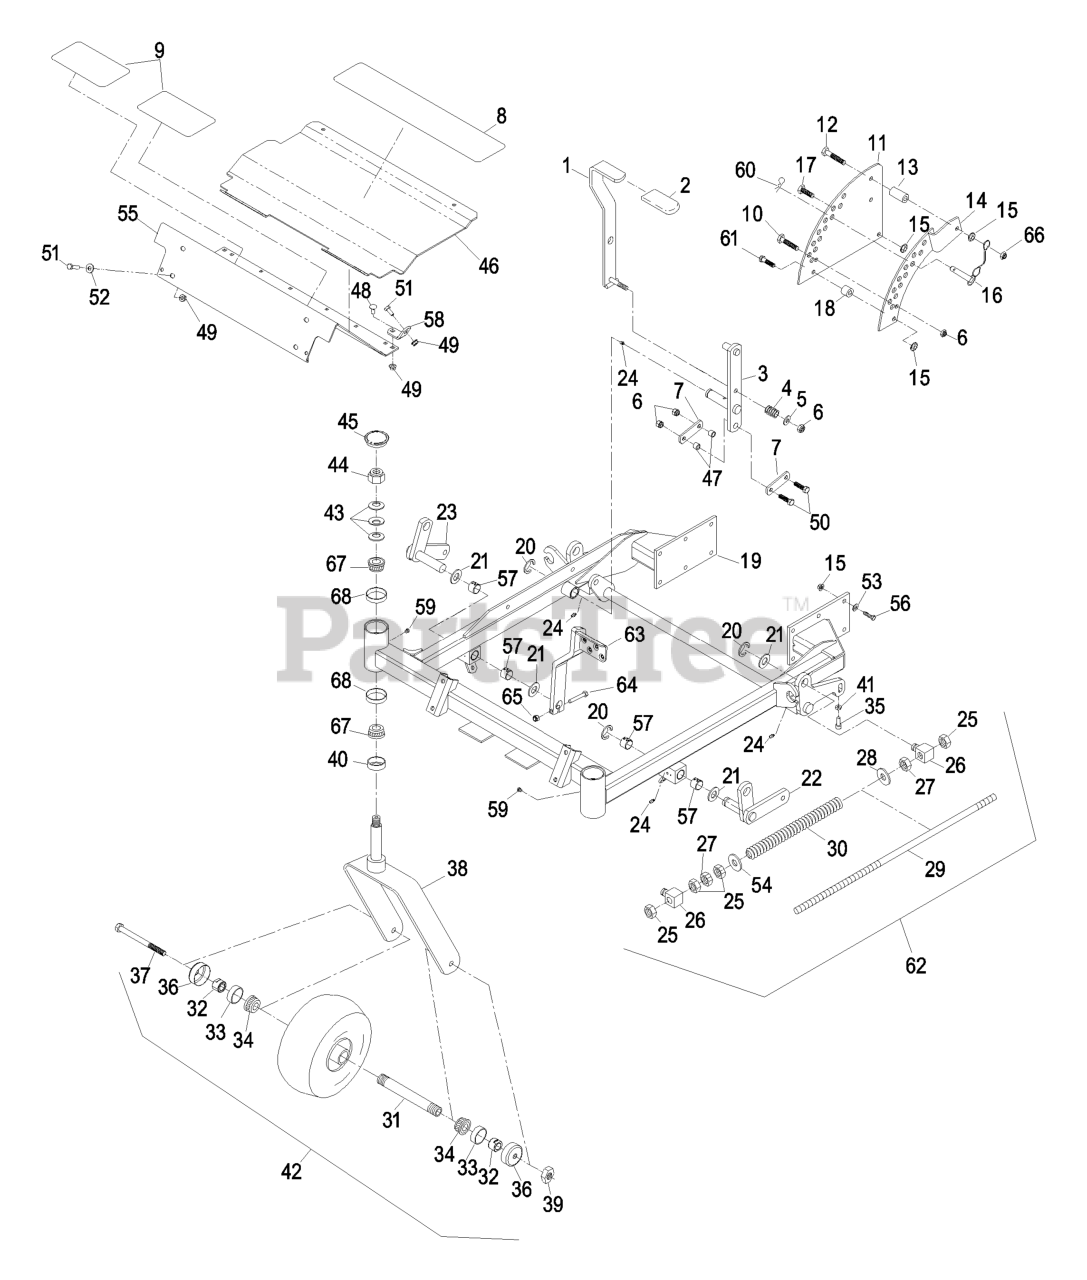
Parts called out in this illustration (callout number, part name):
1	ASM, LIFT LEVER / GRIP
2	GRIP-LEVER, LIFT
3	WLD, DECK LIFT ARM-LHP
4	SPRING-COMPRESSION
5	WASHER-FLAT
6	NUT-LOCK, NI
7	ARM-LIFT, DECK
8	PAD-ANTISKID
9	PAD-ANTI SKID
10	SCREW-HH
11	PLATE-LIFT, DECK
12	SCREW-HH
13	BUSHING-LEVER, LIFT
14	PLATE-LIFT, DECK
15	NUT-HHF, WHIZ
16	PIN-HITCH (W/LANYARD)
17	SCREW-HH
18	BUSHING-LEVER, LIFT
19	KIT, FRONT FRAME-LHP44
20	RING-RETAINING, EXT
21	WASHER-FLAT
22	WLD,SHAFT LH
23	WLD,SHAFT RH
24	FITTING-GREASE
25	NUT-HEX
26	SWIVEL-DECK MOUNT, REAR
27	NUT-JAM
29	ROD-LIFT, DECK
30	SPRING-COMPRESSION
32	SPACER-NUT
33	SEAL-CASTER
34	BEARING-CONE, TAPERED ROLLER
35	SCREW-HSH
36	GUARD-SEAL
37	SCREW-HH
39	NUT-HEX
40	SEAL-GREASE
41	NUT-JAM
43	WASHER-BELLVILLE
44	NUT-LOCK, NI
45	CAP-GREASE
47	BUSHING
48	BOLT-CARR
50	SCREW-HH
51	SCREW-HH
52	WASHER-FLAT
53	WASHER-BELLEVILLE
54	WASHER-FLAT
56	SCREW-HH
57	BUSHING,SPRING
58	BRACKET-FLOORPAN
60	PIN-COTTER
61	SCREW-HH
62	FRONT SPRING ASM
64	SCREW-HH
65	NUTTORQUE ZKPLT
66	NUT-LOCK, NI
67	Cone-Bearing Tapered Roller
68	CUP-BEARING
